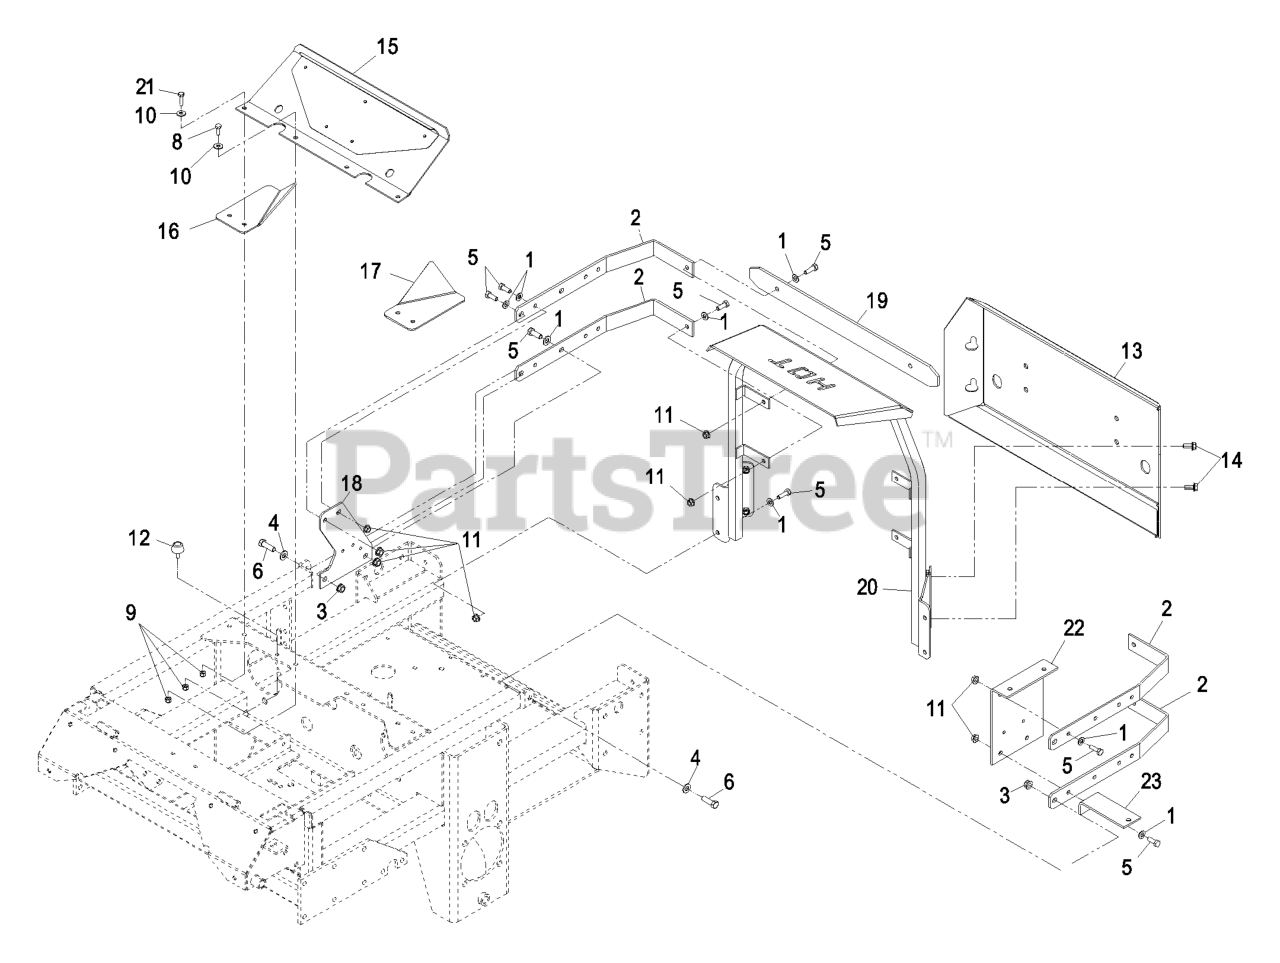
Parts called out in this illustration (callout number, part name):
1	WASHER-PLAIN
2	BAR-MOUNT FRAME, RADIATOR
3	NUT-HHF, WHIZ
4	WASHER-FLAT
5	SCREW-HH
6	SCREW-HH
7	BRACKET, HYD TANK
8	SCREW-HH
9	NUT-LOCK, NI
10	WASHER-FLAT
12	BUMPER-RUBBER
13	WLD,REAR BUMPER
14	SCREW-HHF
15	KIT,FRNT ENG COVER W/DECA
16	SUPPORT-FRONT COVER, RH
17	SUPPORT-FRONT COVER, LH
18	Support, Rib Side
19	GUARD, XS REAR MUFFLER
21	SCREW-HH
22	BRACKET, HYD TANK
23	BRACKET, HYDRAULIC TANK
